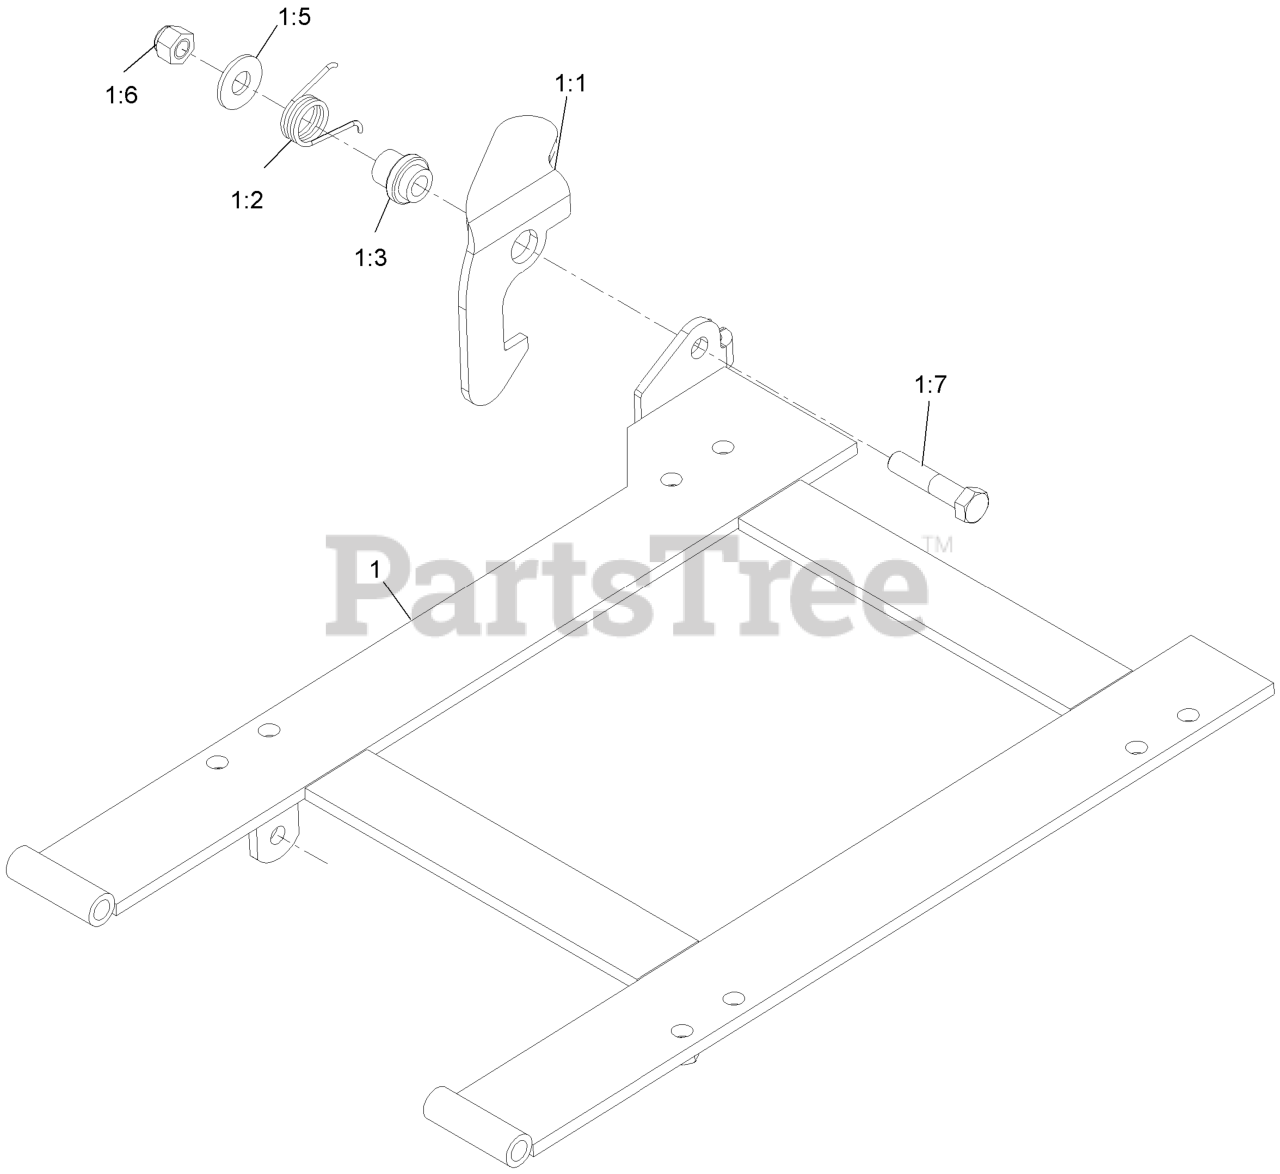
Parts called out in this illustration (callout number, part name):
1	Seat Frame Single Latch ASM
1:1	CATCH-LATCH, SINGLE
1:2	SPRING-TORSION, LATCH
1:3	BUSHING-LATCH, SEAT
1:5	WASHER-FLAT
1:6	NUT-LOCK, NI
1:7	SCREW-HH
